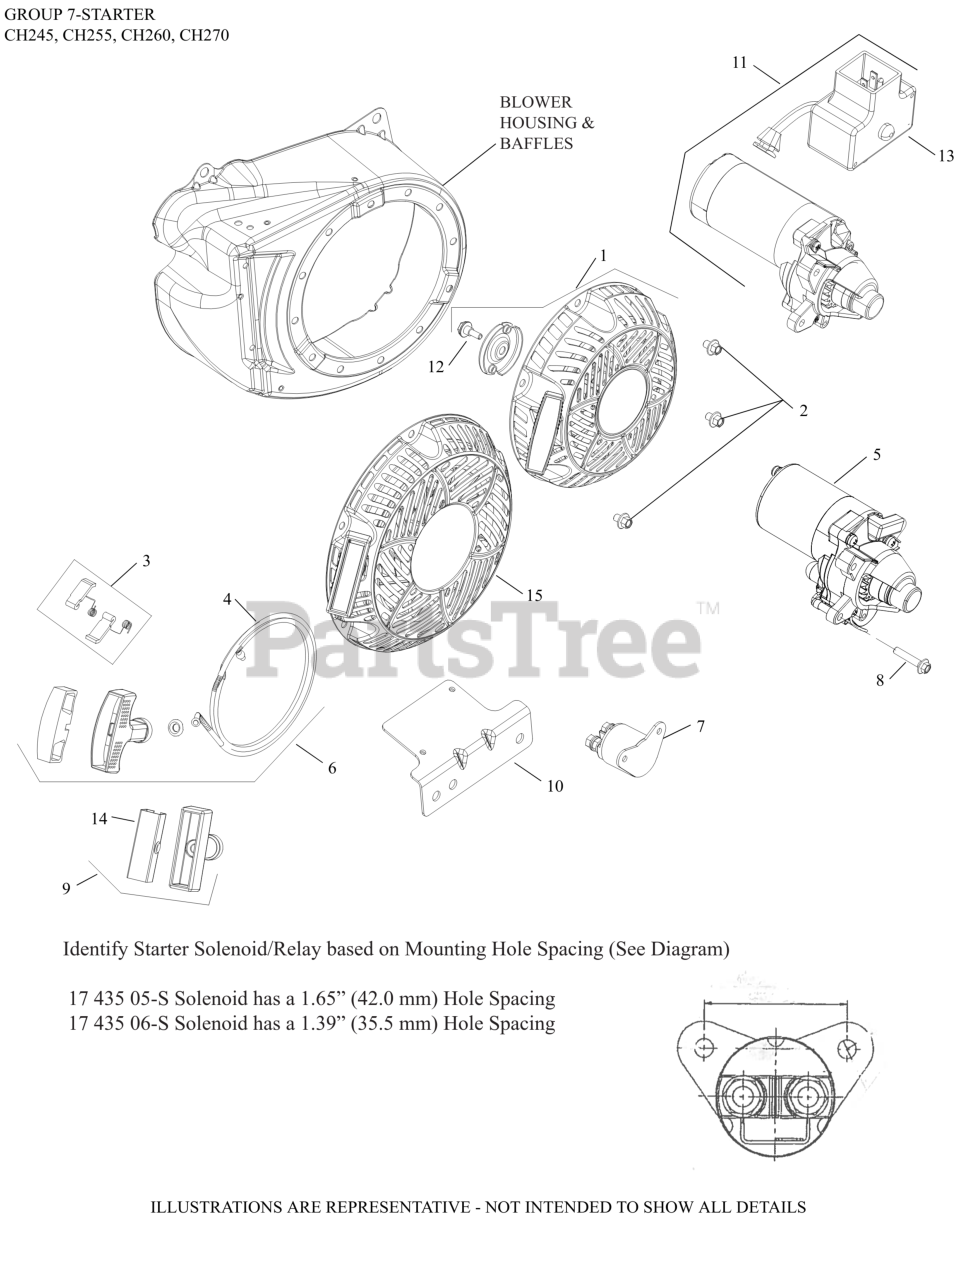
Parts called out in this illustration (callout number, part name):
1	STARTER ASSEMBLY, RETRACTABLE
2	SCREW, M6 X 8 HEX FLANGE HEAD
3	KIT, PAWL REPAIR
4	ROPE, STARTING
5	ELECTRIC STARTER-BENDIX DRIVE
6	KIT, STARTER ROPE W/HANDLE
8	SCREW, STARTER MOUNTING
12	SCREW, SHOULDER (M5)
